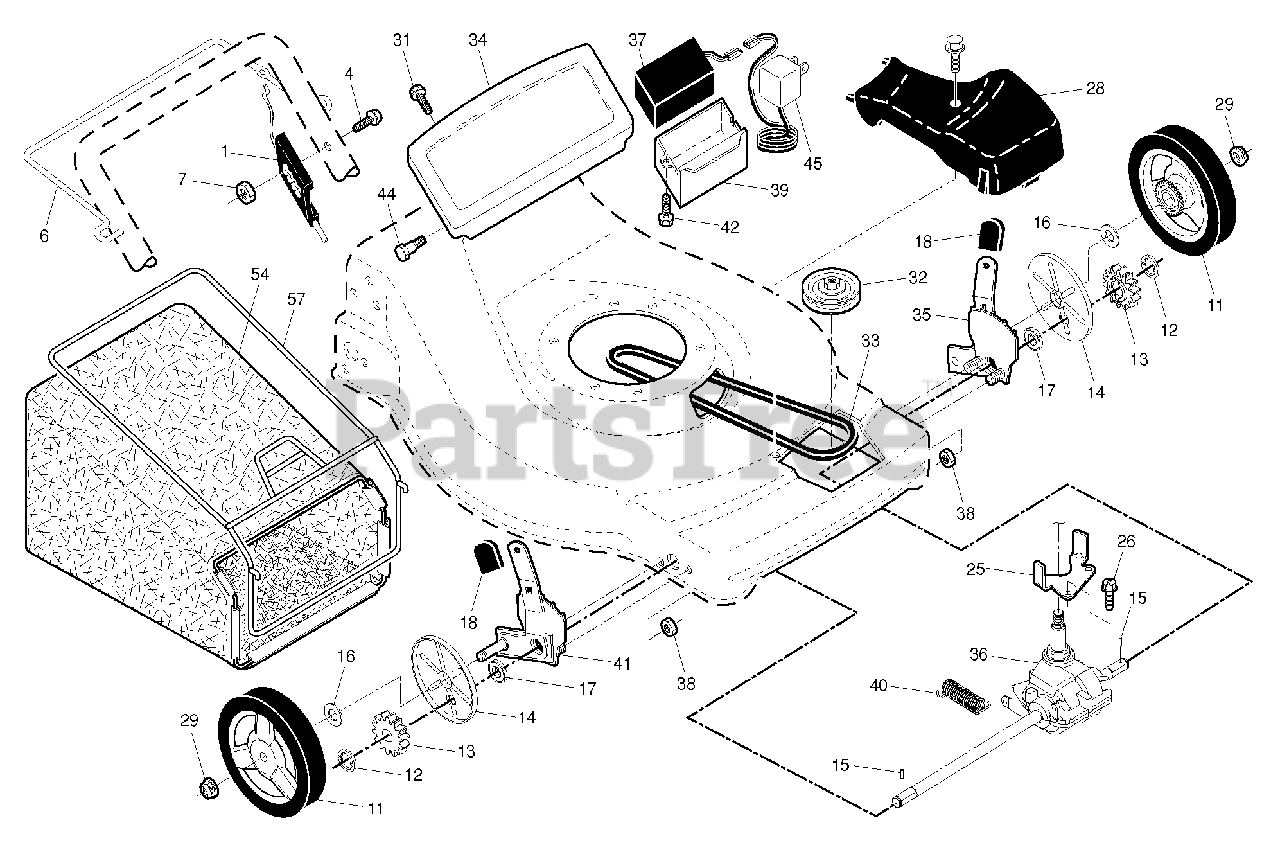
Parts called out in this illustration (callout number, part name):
1	CABLE.DR.VS.BOLT-ON.AUTO.FGD L
6	BAIL.CONT.DR.S/S.ROUND.ORG
7	NUT.HEX.FLANGE.1/4
11	WHEEL.8X1.75.H3SPK.RAD3.GY.BU3
12	E-RING 7/16 RE
13	PINION.14.TEETH.FGD
14	COVER.DUST.WHEEL
15	PAWL, DRIVE
16	WASHER FLUT
17	RP BEARING.ASM.
18	SELECTOR KNOB
25	BRACKET.BELT.GUIDE.22+FGD.BZP
28	COVER.DR.ASM.194407X498.CE
29	NUT.HEX.FLANGE.3/8-16.LO(3 2)
31	SCREW.PAN.HEAD.#10
32	RP PULLEY.DRIVE.EZ/VAR.SCREWON
33	BELT.DRIVE.FG
34	PANEL.TRIM.21.FWGD.ES
35	KIT ADJUSTER ASM.438151.
36	TRANSMISSION.22.VS.FWGD
37	BATTERY WITH AMP CONNECTOR
38	LOCKNUT.NYLOC.1/4-20
39	BOX.BATTERY.TRIM
41	KIT ADJUSTER ASM.438148
42	SCREW.HWH.13-16X.50
44	SCREW.SHOULDER.HH.10X.281X.6
45	RP CHARGER.12V.0.1A
54	GBAG.83230247T.SIL.HUSQ.BLU
57	FRAME.GBAG.22.EZ.EMPTY.SC
